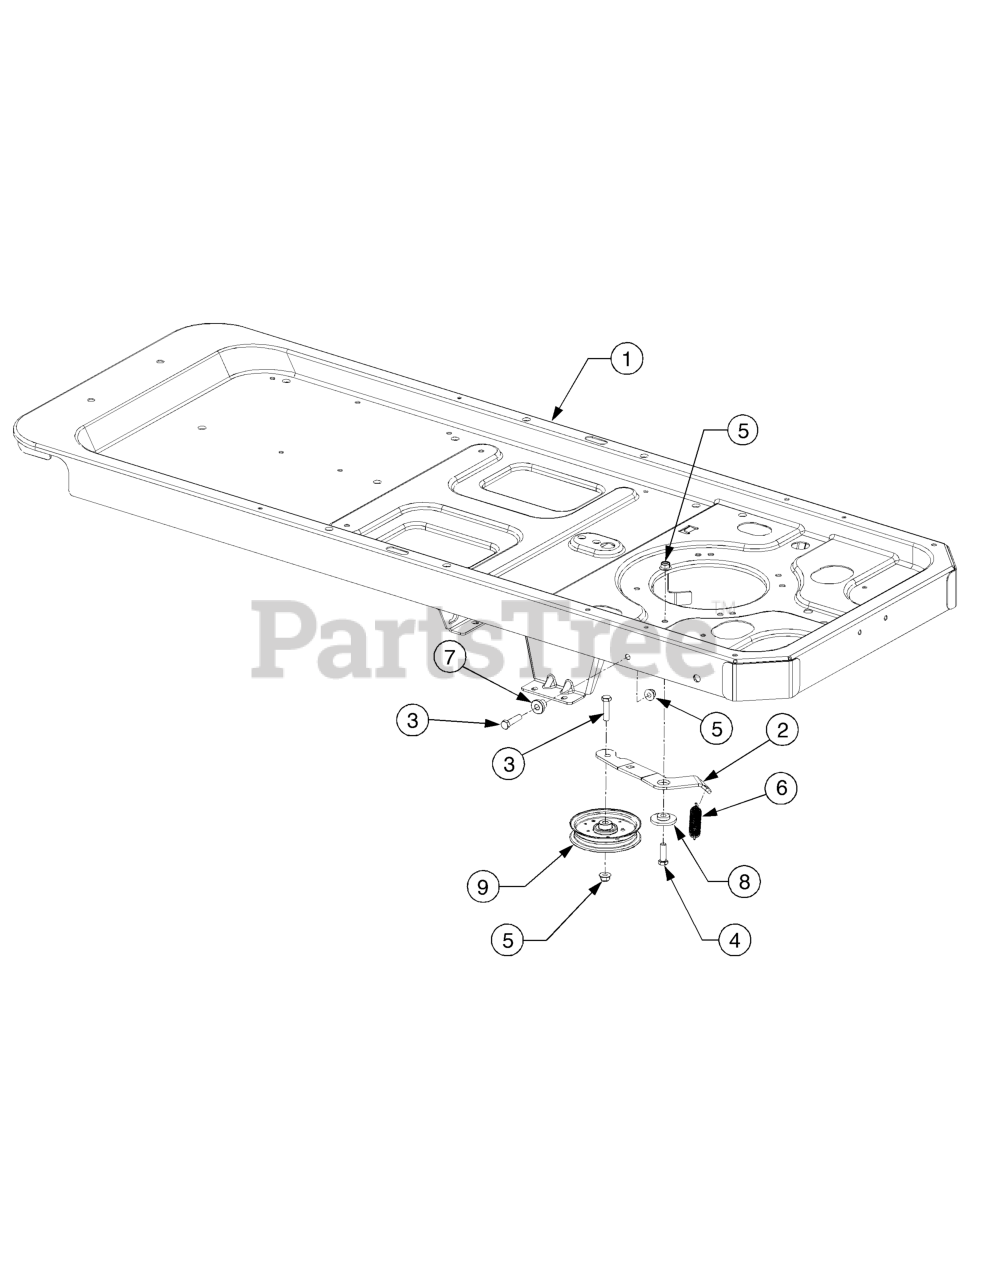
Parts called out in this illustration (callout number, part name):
1	Graphic, Release Lever
3	Screw, Hex Cap, 3/8-16 x 1.5 GR5
4	Screw, Hex Cap, 3/8-16 x 1.25 GR5
5	Nut, Hx Insert Flange Lck, 3/-16 GRF
6	Spring, Extension, .75 x 5.06
7	Spacer, Shoulder, .39 x 1.0 x .7
8	Screw, Shoulder, .884 x .19
9	Pulley, Idler, 4.25 Dia.
